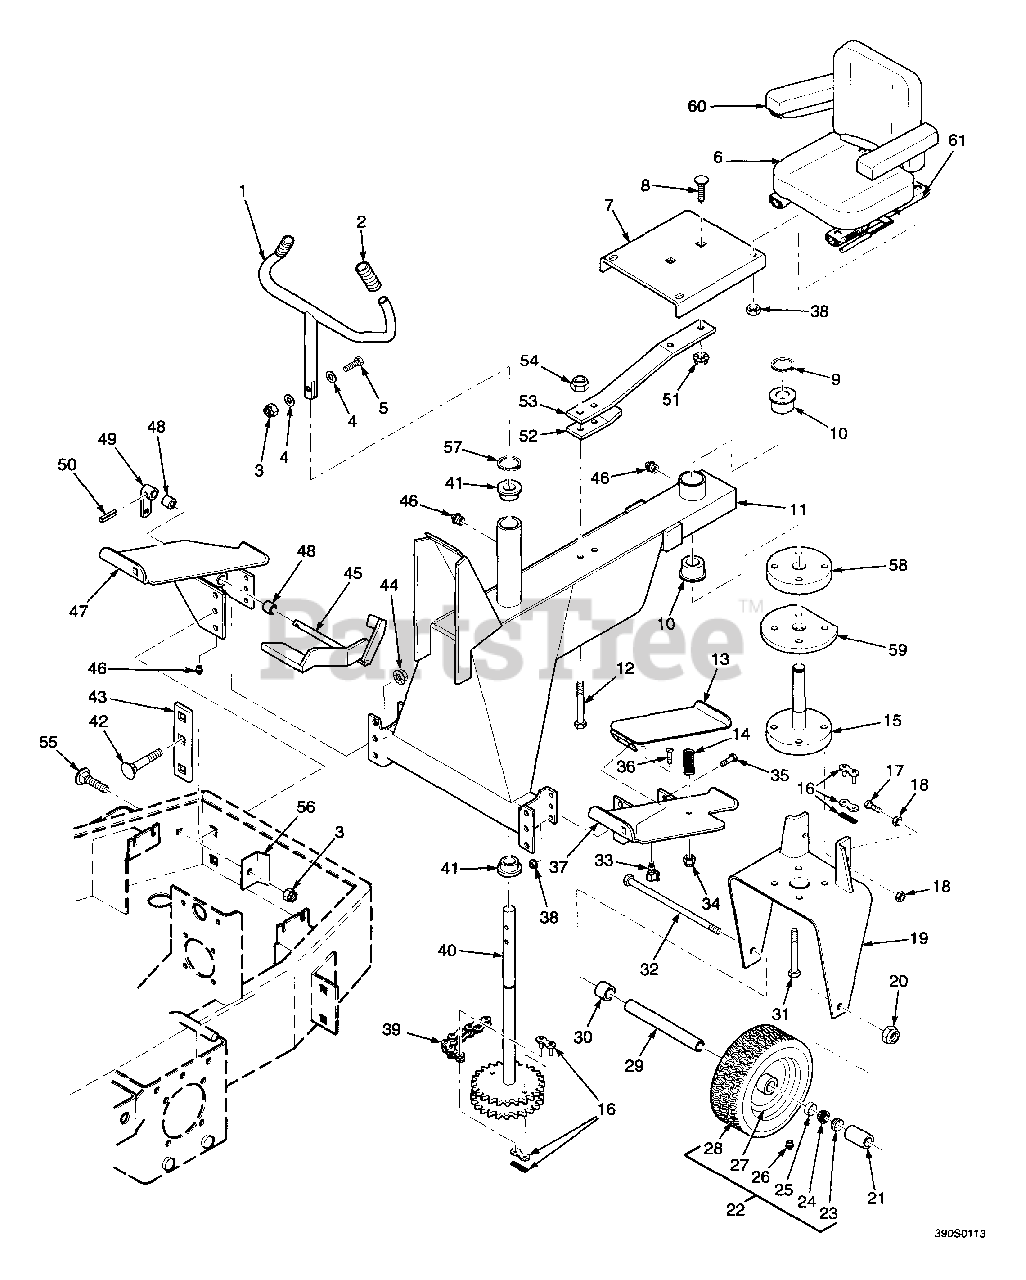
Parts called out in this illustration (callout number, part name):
1	Handle, Steering
2	Handle Grip
3	Hex Locknut, Elastic Stop, 5/16-18
4	Flatwasher, 5/16 (.375 x.875 x 083)
5	Bolt, Hex Head, 5/16-18 x 1.75
6	Seat With Adjuster Rails
7	Plate, Seat Mount
8	Carriage Bolt, 3/8-16 x 1-1/4
9	Retaining Ring - 1.125 Ext
10	Bushing, Oilite - 1-1/8 ID
11	Frame, Steering
12	Bolt, Hex Head, 7/16-14 x 3-1/2
13	Pedal, Foot Interlock
14	Spring, Foot Interlock Switch
15	Pivot, Rear Yoke
16	Connector Link, #50 Chain
17	Anchor Bolt, Chain
18	Nut, Jam, 3/8-16
19	Yoke, Rear
20	Hex Locknut, Elastic Stop, 5/8-11
21	Spacer, Rear Wheel
22	Rear Wheel Assembly
23	Seal, Grease
24	Bearing Cone
25	Bearing Cup
26	Grease Fitting
27	Rim
29	Sleeve, Rear Tire
30	Spacer, Rear Wheel
31	Bolt, Hex Head, 7/16-14 x 2-1/2
32	Bolt, Hex Head, 5/8-11 x 11-1/4
33	Switch, Foot Interlock
34	Hex Locknut, Elastic Stop, 1/4-20
35	Serr Fl. Hex Head Capscrew, 5/16-18 x 1.00
36	Screw, Flat , #10-32 x 3/4
37	Footplate, LH
38	Serr. Fl. Hex Nut, 5/16-18
39	Chain, Steering - #50
40	Shaft, Steering
41	Bushing, Bronze - #77 ID
42	Carriage Bolt, 1/2-13 x 1-3/4
43	Pad, Reinforcement
44	Serr. Fl. Hex Nut, 1/2-13
45	Foot Pedal
46	Grease Fitting
47	Footplate, RH
48	Bushing, Oilite - 3/4 ID
49	Foot Pedal Arm
50	Pin, Drive Lock, 3/16 x 1-1/4
51	Serr. Fl. Hex Nut, 3/8-16
52	Reinforcement, Spring
53	Spring, Seat Support
54	Hex Locknut, Elastic Stop, 7/16-14
55	Carriage Bolt, 5/16-18 x 3/4
56	Retainer, Bolt
57	Retaining Ring, 7/8 Ext
58	Guide, Top Chain
59	Divider, Chain Spacer
60	Arm rest Assembly
61	Track Set, Seat
